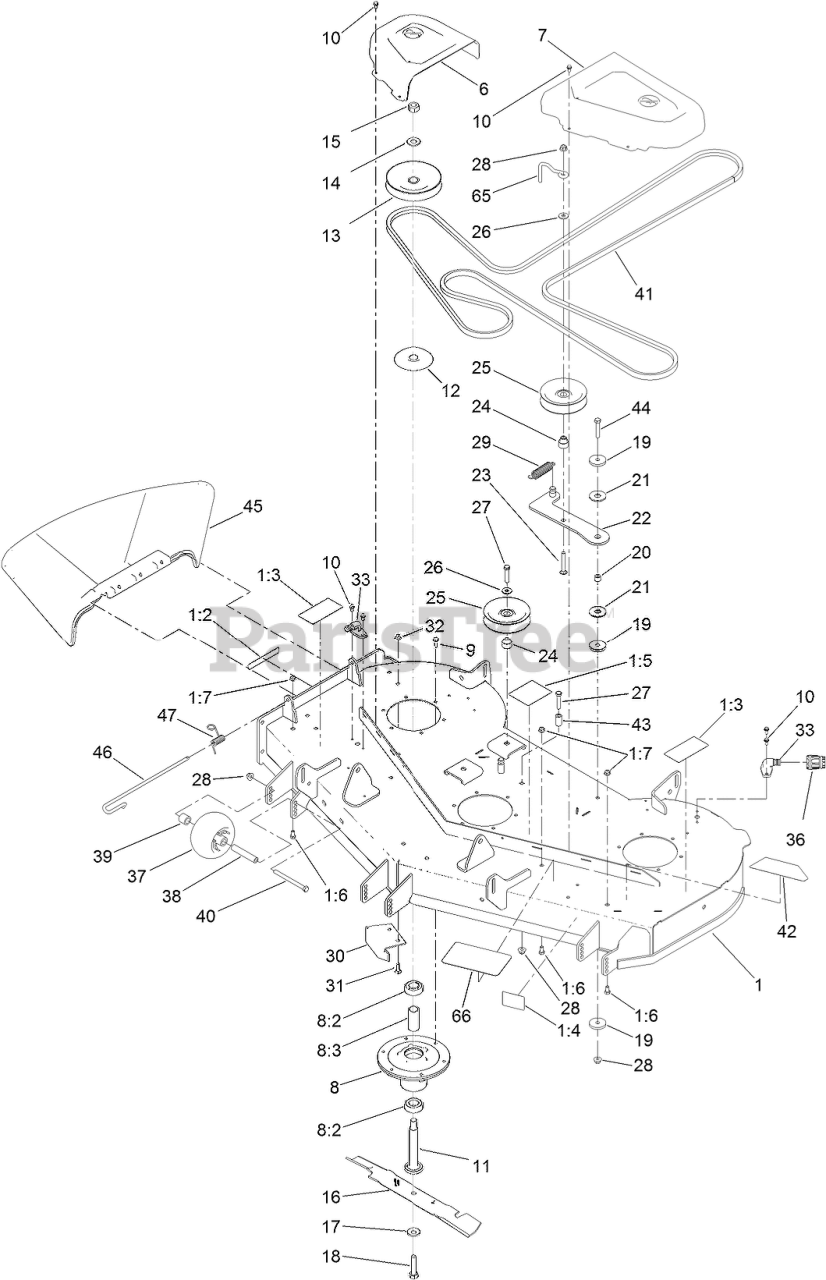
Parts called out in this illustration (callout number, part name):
1	DECK ASM
1:2	DECAL-DANGER
1:3	DECAL-DANGER, DECK
1:4	DECAL-SCALP, ANTI
1:5	DECAL-ROUTING, BELT
1:6	SCREW-HH
1:7	NUT-HF, NI
6	COVER-BELT, RH
7	COVER-BELT, LH
8	SPINDLE ASM
8:2	BEARING-BALL
8:3	SPACER-BEARING
9	SCREW-TAPTITE
10	SCREW-HWH
11	SHAFT-SPINDLE
12	SHIELD-BEARING
13	PULLEY
14	WASHER
15	NUT-HEX
16	BLADE-HI FLO
17	WASHER-BELLEVILLE
18	SCREW-BLADE
19	WASHER-PLAIN
20	BUSHING-LEVER, LIFT
21	WASHER-FRICTION, COMPOSITE
22	ARM-IDLER
23	SCREW-CARR
24	BUSHING-IDLER
25	PULLEY-IDLER, FLAT
26	WASHER-HARDENED
27	SCREW-HH
28	NUT-HF, NI
29	SPRING-EXTENSION
30	BAFFLE-CUTOFF
31	SCREW-CARR
32	NUT-HF, NI
33	FITTING-WASHOUT
36	CONNECTOR-HOSE
37	ROLLER-SCALP, ANTI
38	TUBE-SPANNER
39	SPACER-AXLE, REAR
40	SCREW-HH
41	V-BELT
43	SPACER
44	SCREW-HH
45	DEFLECTOR-DISCHARGE
46	PIN-CHUTE
47	SPRING-TORSION
65	GUIDE-BELT, IDLER
66	TREAD-STEP
